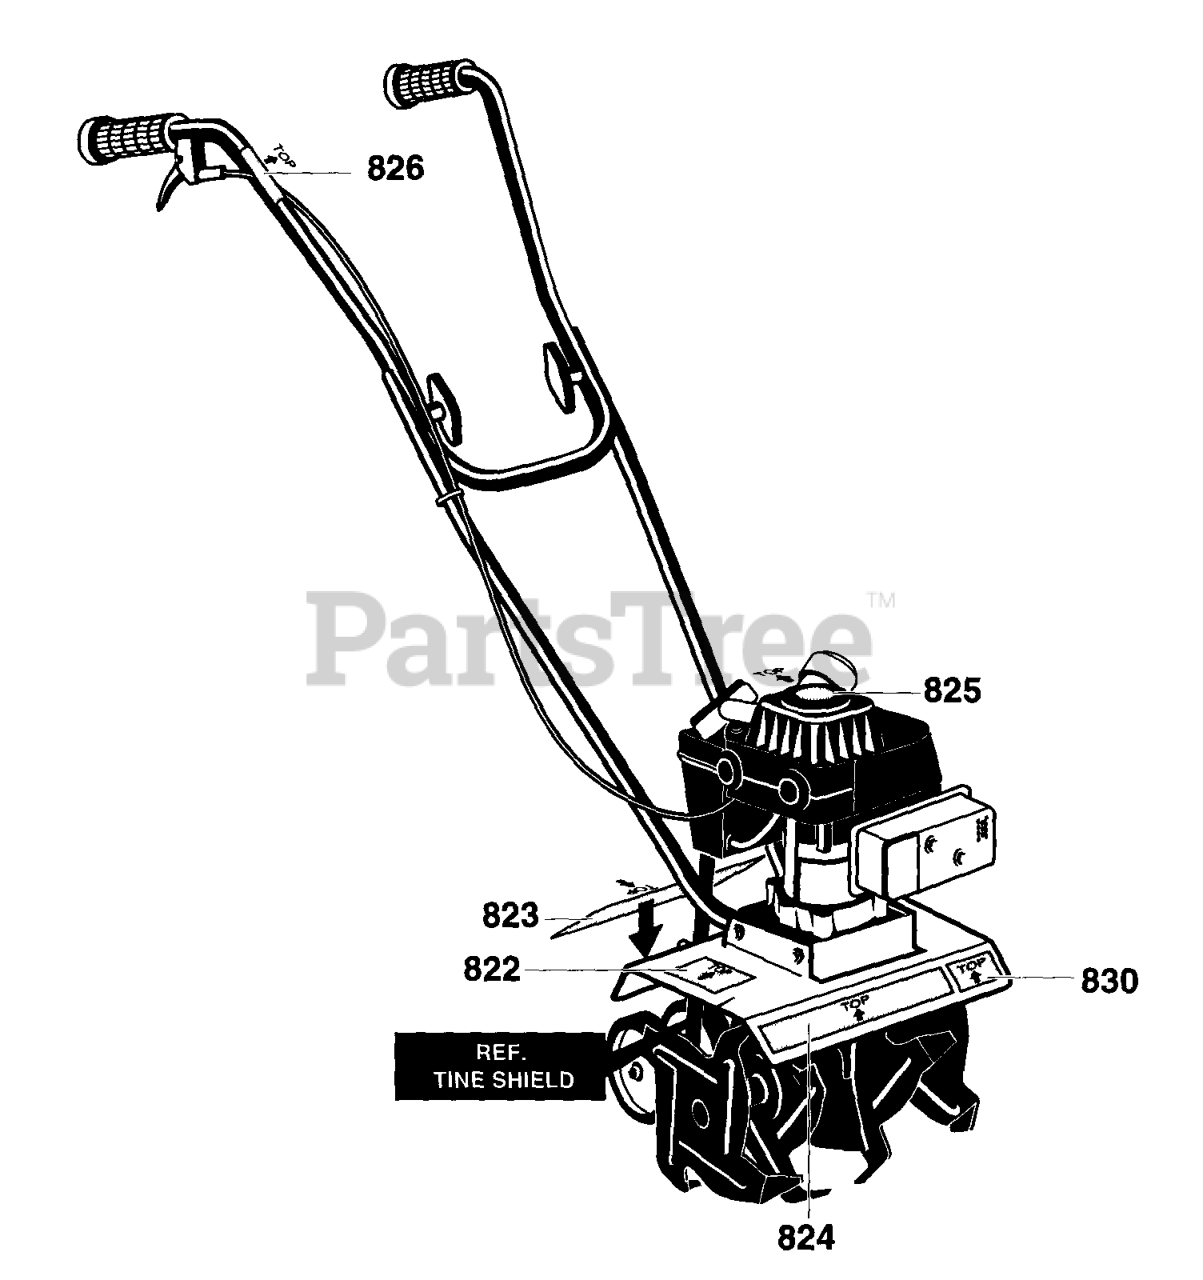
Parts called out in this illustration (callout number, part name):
824	DECAL, HUSQVARNA TOP COVER
825	DECAL,RECOIL COVER HUSQV.EDGER
826	DECAL CT16
830	DECAL, HUSQ CT-16
